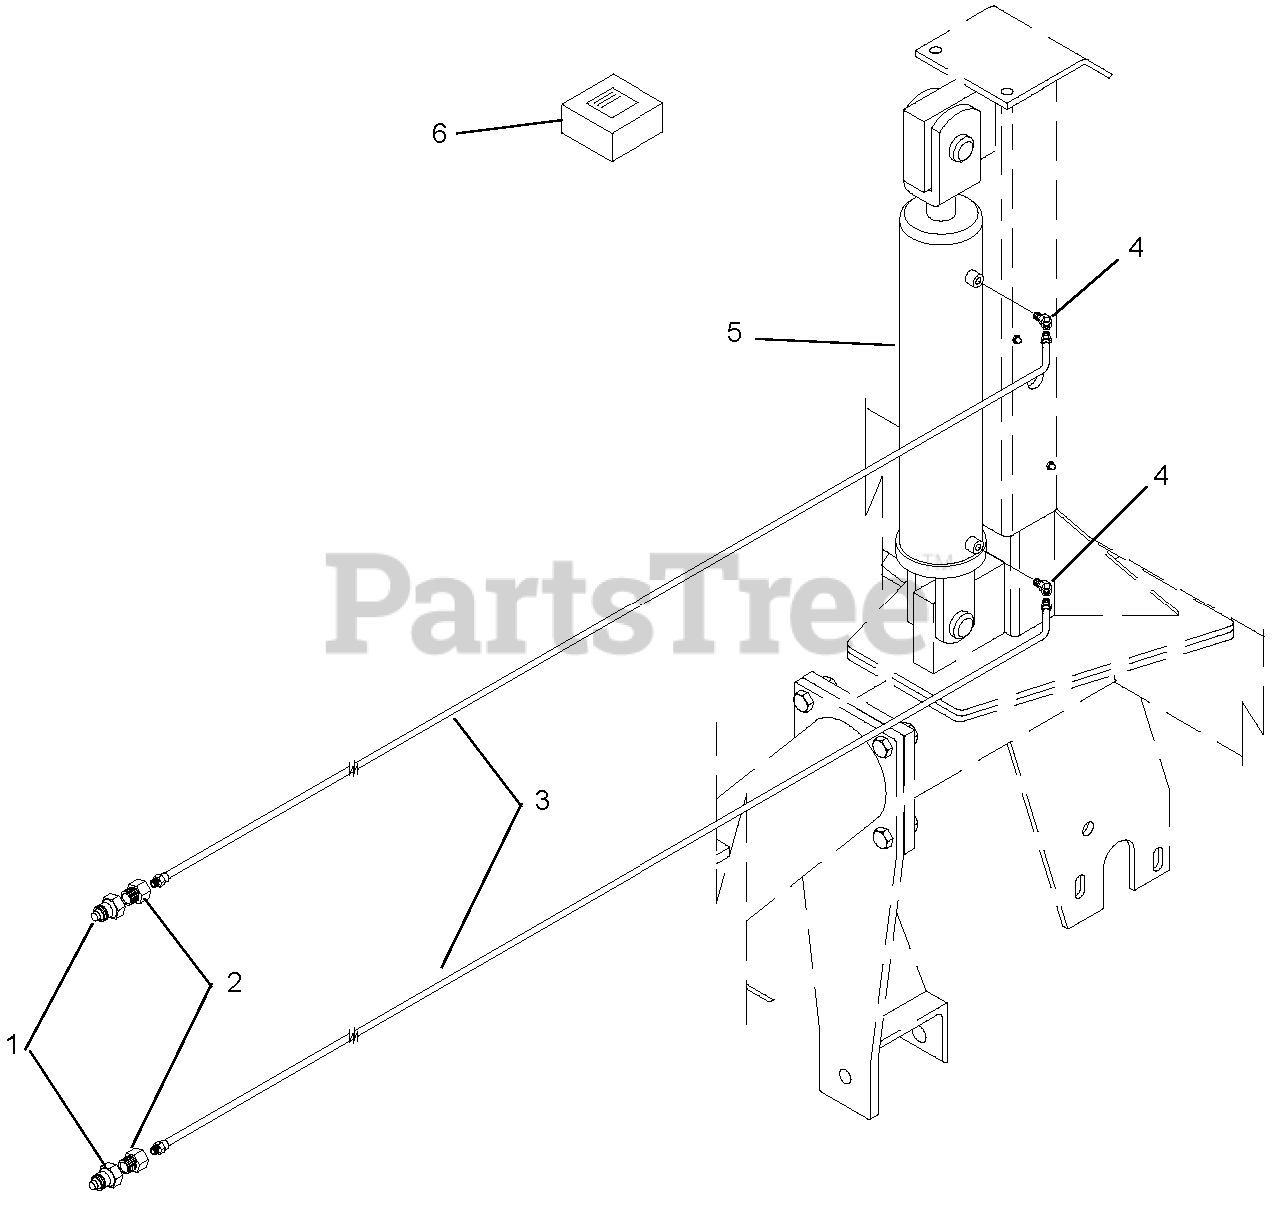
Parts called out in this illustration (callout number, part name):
1	Coupler, .50 FNPT QD Male
2	Adapter, .50 MNPT x .25 FNPT
3	Hose Assembly 120-Inch
4	Adapter .25 FNPT x .25 MNPT
5	Cylinder, Hydraulic
6	Seal Kit
